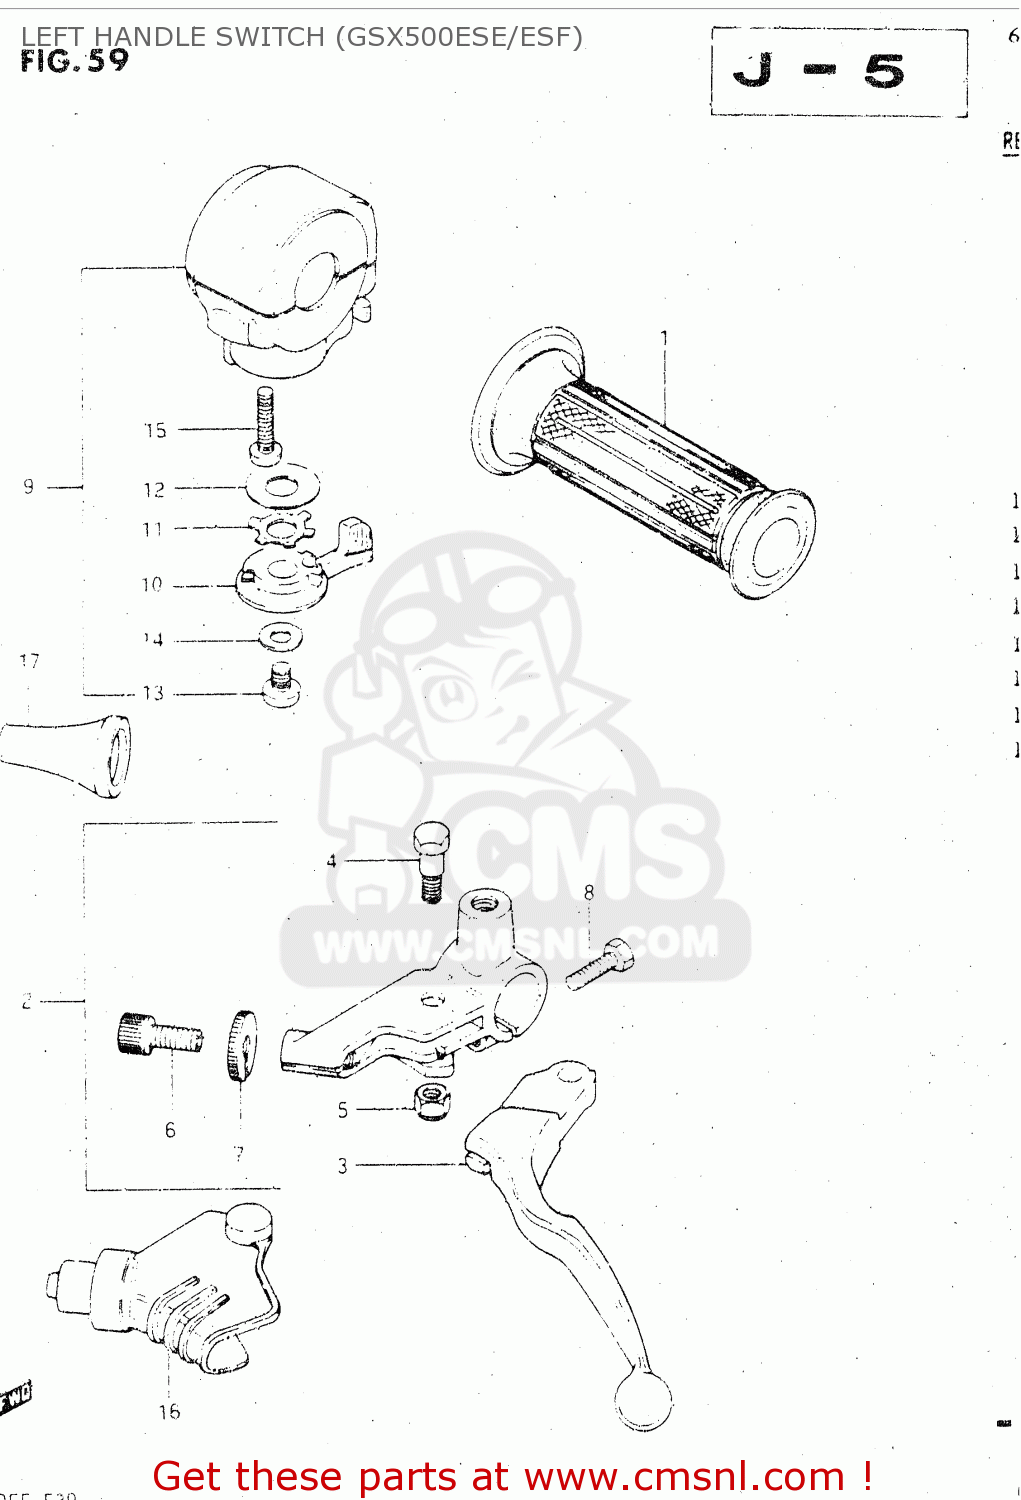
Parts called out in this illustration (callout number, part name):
1	GRIP,L
2	LEVER ASSY,CLU
3	LEVER,CLUTCH
4	BOLT,LEVER
5	NUT
6	ADJUSTER,CABLE
7	NUT,CABLE ADJUSTER
8	BOLT
9	SWITCH ASSY,HA
10	LEVER,STARTER
11	WASHER
12	WASHER
13	SCREW
14	WASHER
15	SCREW
16	COVER,CLUTCH LEVER
17	BOOT,CLUTCH CABLE
